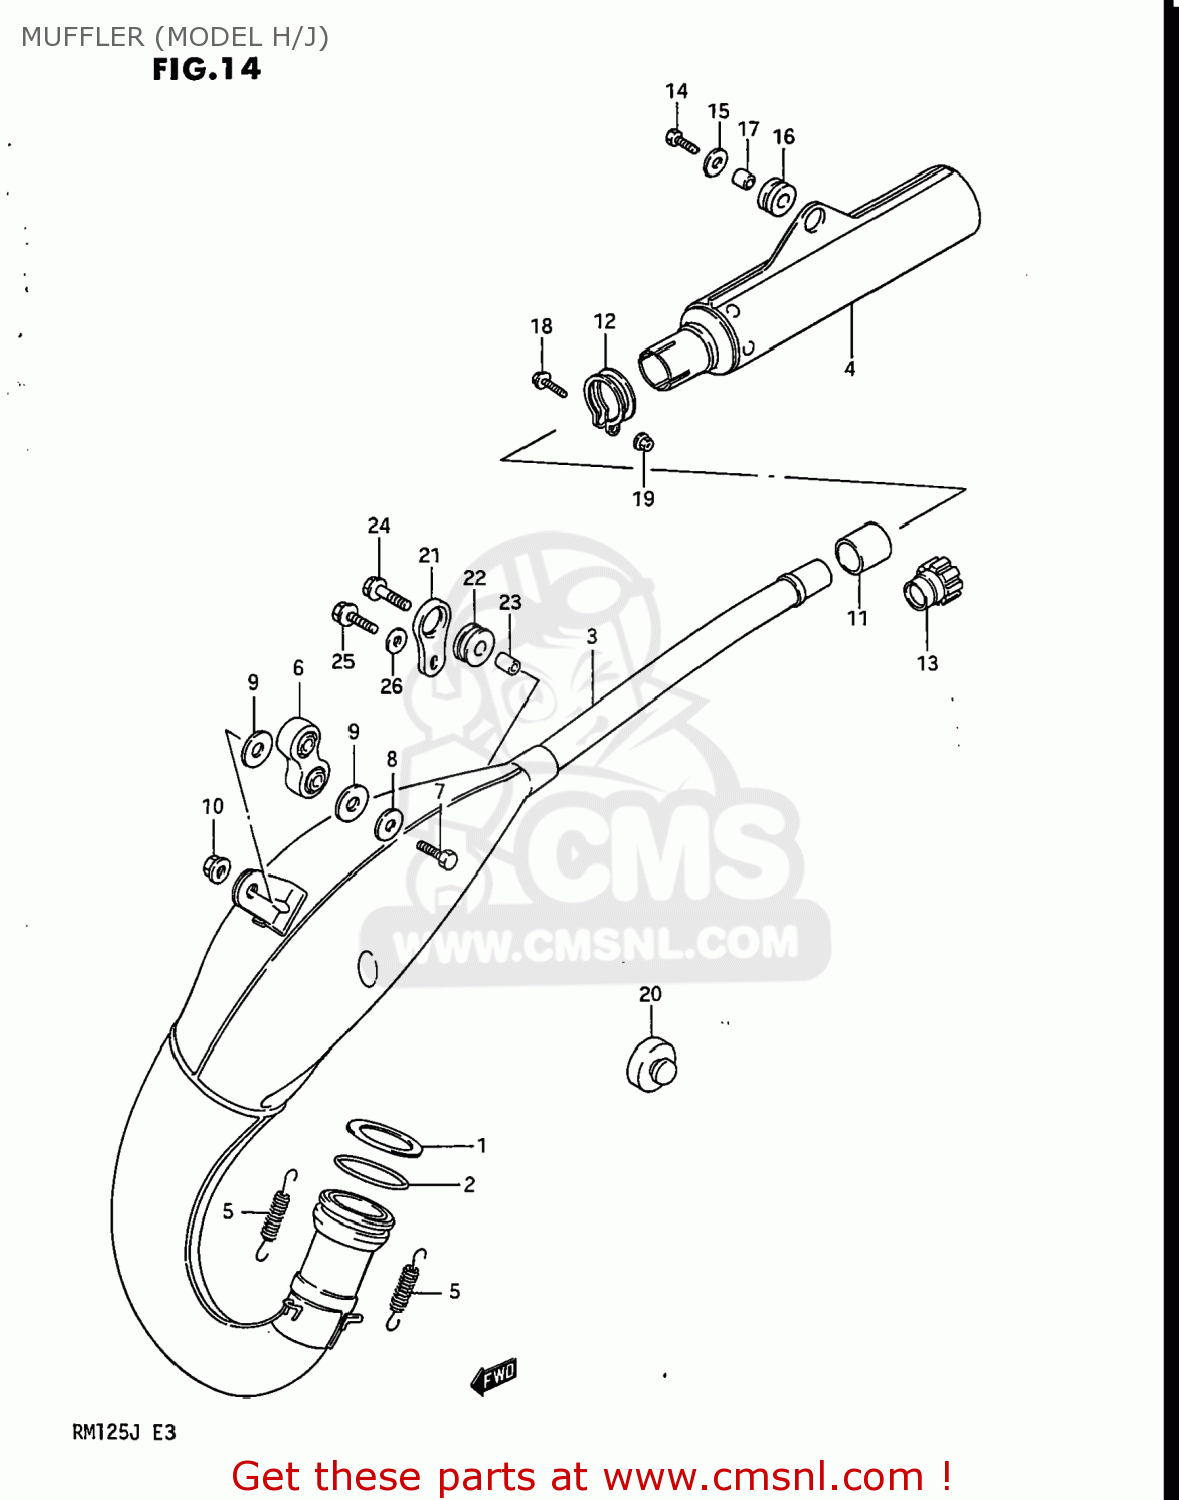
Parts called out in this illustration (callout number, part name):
1	GASKET,EXHAUST PIPE (NAS)
2	O-RING,EXHAUST
3	MUFFLER RM 125
4	MUFFLER,SECOND
5	SPRING
6	DAMPER,MUFFLER
7	BOLT(8X32)
8	WASHER
9	WASHER(13X28X1.6)
10	NUT
11	GASKET,SECOND MUFFLER (NAS)
12	CLAMP,SECOND MUFFLER
13	CONNECTOR,MUFFLER
14	BOLT
15	WASHER (6.5X24X1.6)
16	CUSHION
17	SPACER (6.4X9X10.5)
18	BOLT 6X35
19	NUT 6MM
20	CUSHION
21	PLATE,MUFFLER MTG
22	CUSHION,MUFFLER
23	SPACER (6.4X9X13.5)
24	BOLT
25	BOLT
26	WASHER
